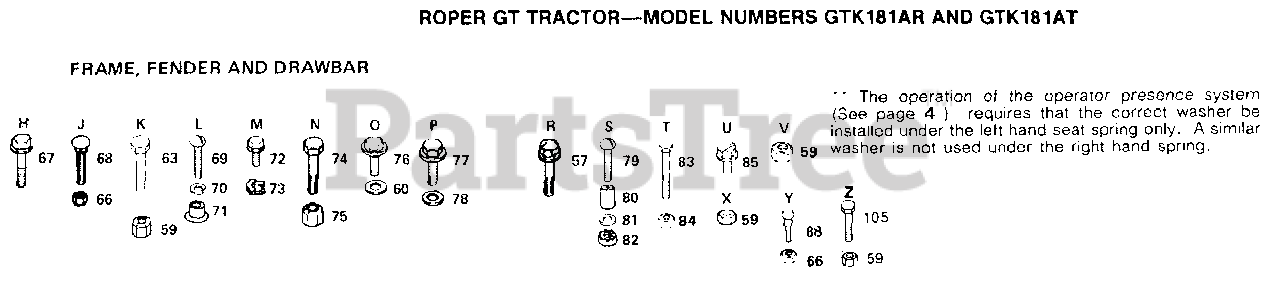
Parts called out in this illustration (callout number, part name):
57	SCREW
60	WASHER 9/32 X 3/4 X 16 GA..
63	BOLT
68	BOLT
69	SCREW
70	LOCKWASHER
71	WELDNUT
73	"""J"" FASTENER LT"
74	BOLT T
76	SCREW
77	SCREW
78	WASHER
79	SCREW
80	SPACER LT
81	WASHER
83	BOLT
84	NUT GTV
85	SCREW LT
